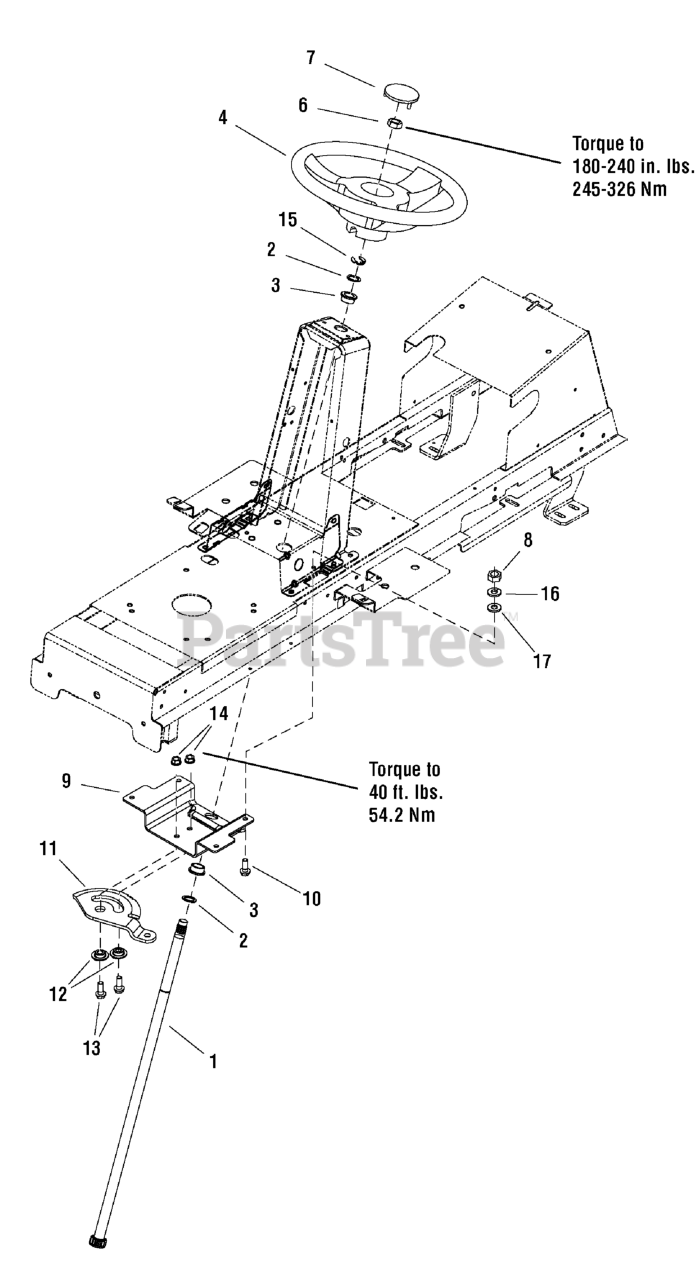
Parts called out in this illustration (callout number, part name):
1	SHAFT, Steering Gear & Spline
2	WASHER, 3/4
4	STEERING WHEEL
6	NUT, Hex Lock, ESNA Light, 5/8-18
7	CAP, Steering Wheel
9	BRACKET, Sector Support
10	BOLT, M8 x 25
11	GEAR, Steering .250 THK 26 Teeth
12	SPACER, Sector Gear
13	SCREW, Hex LK Flange 3/8-16 x 1.00
14	NUT, Hex-Flange 3/8-16 LK
15	RING, Klipring
16	WASHER, 8.4
17	WASHER, 8
